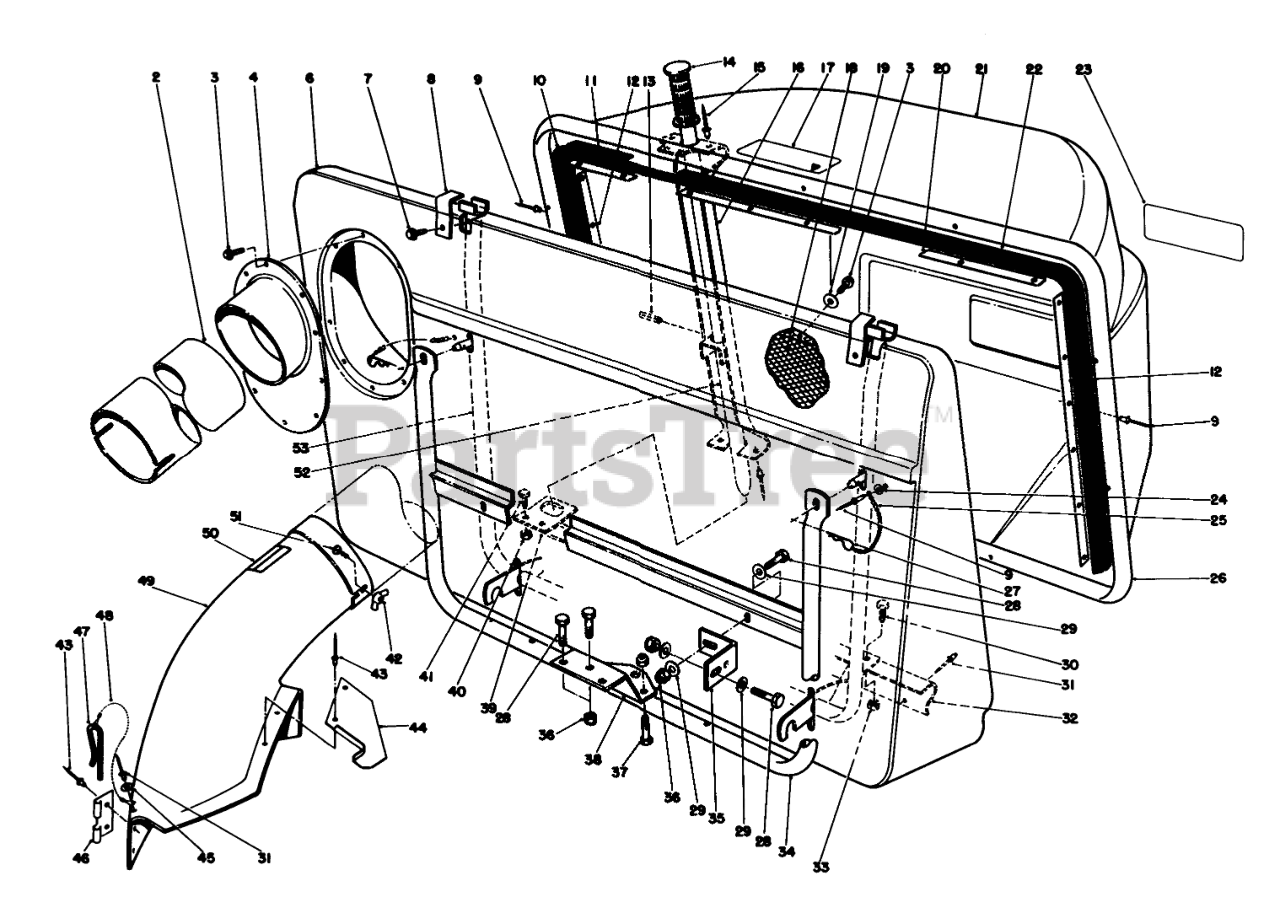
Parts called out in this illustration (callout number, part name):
2	TUBE(ROUND&LONG)
3	SCREW-HWHTF
4	Adaptor-Duct
6	Bag Front
7	SCREW-HWH
8	RETNR PIVOT BRKT
9	Rivet-Pop
10	RH BAG SEAL
11	RETNR TOP EXT.
12	BAG RETNR EXT.
13	PIN-ROLL
14	Grip Handle
15	Rivet
16	DUMP HDLE CHANL WA
17	Decal Warning
18	Screen Bag
19	WASHER-FLAT
20	EXTRUSION BAG RETAINER
21	REAR GRASS BASKET
22	Seal-Bag LH.
23	EASY EMPTY BAG DECAL
24	WASHER
25	10 LINK CHAIN W/O HOOK
26	BAG SUPT ASM FRM
27	PIN-HAIR
28	Screw
29	WASHER-PLAIN
30	SCREW-HH
31	RIVET-BLIND
32	FRAME SUPT BRKT B
33	NUT-LOCK, CONE
34	BAG SUPPORT WA
35	MTG BRACKET
36	NUT-LOCK, NI
37	SCREW-HH
38	MTG PLATE B
39	Hanger-Frame Lower
41	SCREW-HH
42	NUT-WING SPECL
43	Rivet
44	CHUTE SUPT BRKT
45	WASHER-PLAIN
46	BRACKET-MOUNTING, CHUTE
47	PIN-LOCKING, CHUTE
48	LANYARD
49	Chute Assembly (Incl. Ref. #31, 41-50)
50	DECAL-DANGER
51	BOLT-CARR
52	DUMP HANDLE ASM
53	Bag Frame
